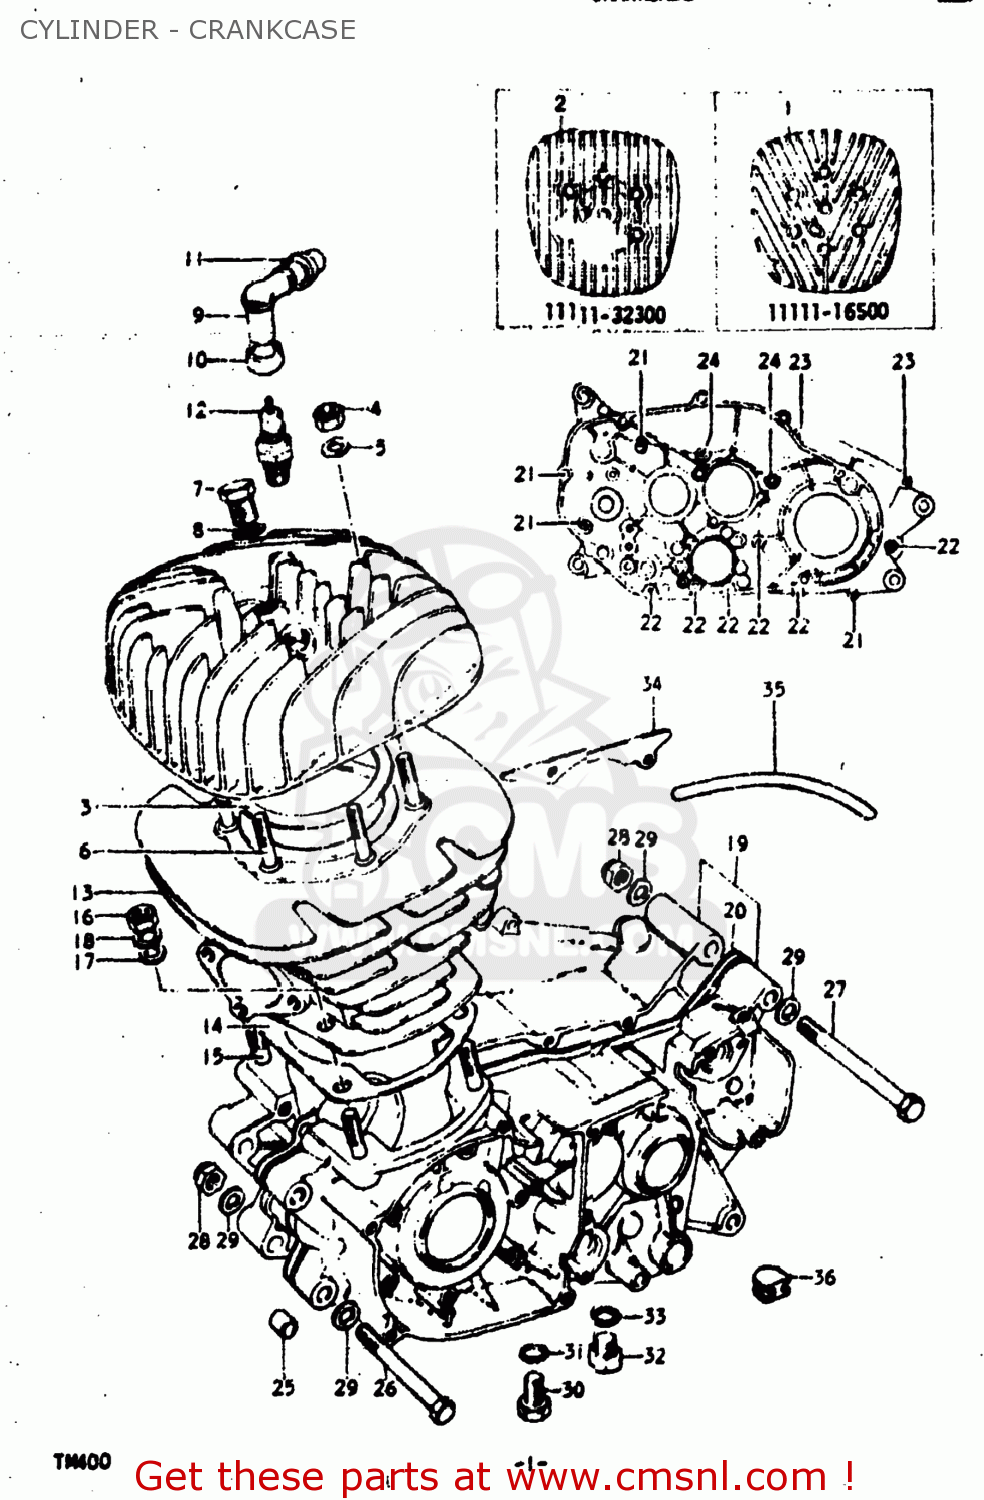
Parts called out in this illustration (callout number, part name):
1	HEAD,CYLINDER
2	HEAD,CYLINDER
3	GASKET,CYLINDER HEAD (NAS)
4	NUT (8MM)
5	WASHER
6	BOLT,STUD
7	PLUG
8	GASKET(14X19.2X2) (NAS)
9	CAP,SPARK PLUG
10	SEAL,SPARK PLUG
11	SEAL,HIGH TENSION CORD
12	SPARK PLUG
13	CYLINDER
14	GASKET,CYLINDER (MCA)
15	STUD BOLT
16	NUT
17	WASHER
18	LOCK WASHER
19	CRANKCASE SET
20	GASKET,CRANKCASE (NAS)
21	SCREW
22	SCREW 6X60
23	SCREW 6X70
24	SCREW 6X80
25	PIN
26	BOLT
27	BOLT
28	NUT
29	WASHER
30	PLUG
31	GASKET(10X14X3.6) (NAS)
32	PLUG
33	GASKET(14X19.2X2) (NAS)
34	PLATE,OIL RESERVOIR
35	HOSE
36	PLUG
